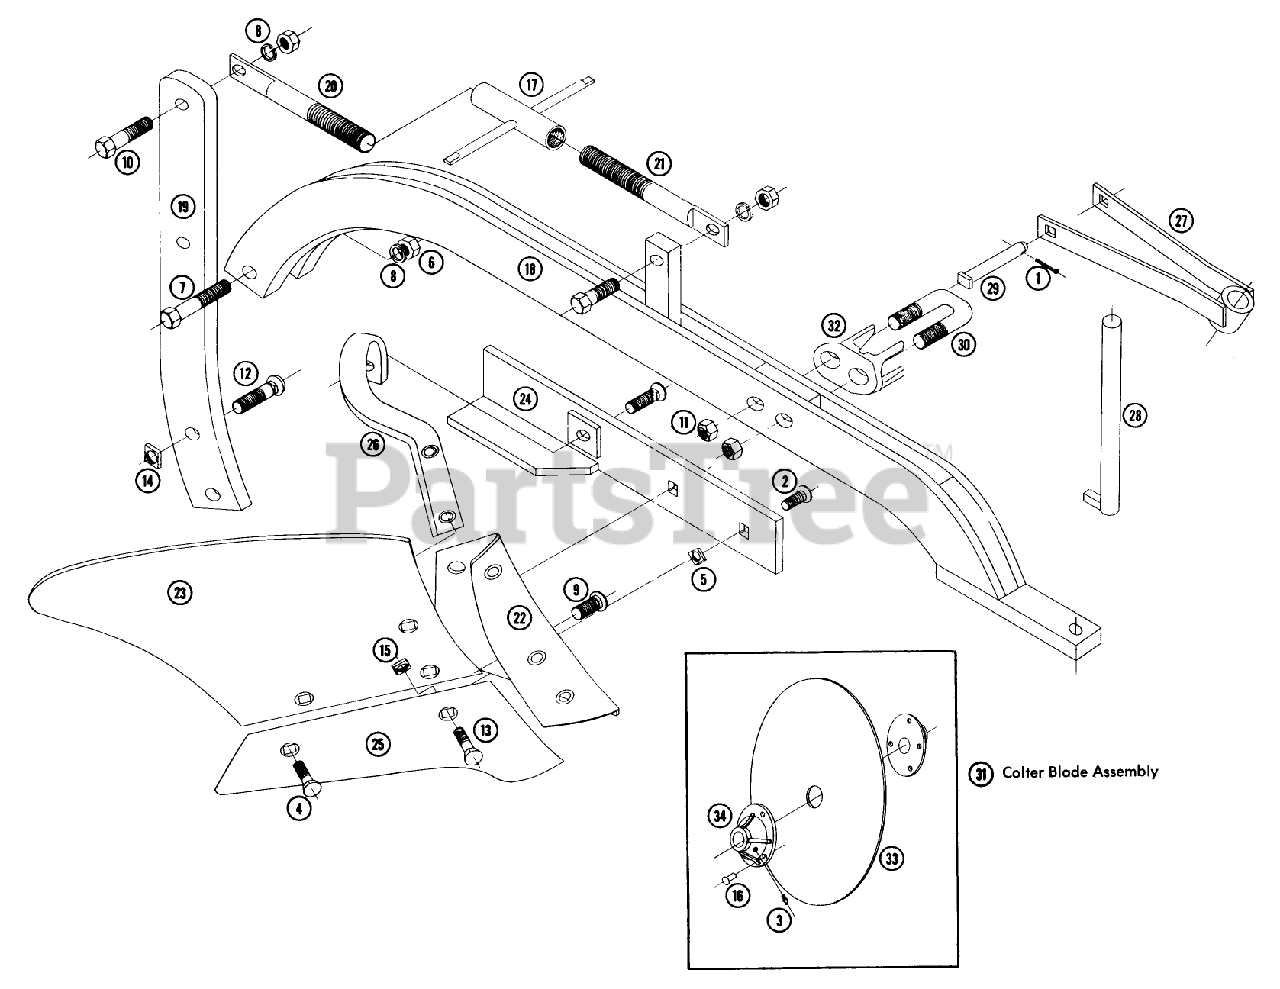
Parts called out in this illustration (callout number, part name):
1	Cotter Key
2	Bearing
4	Plow Bolt w/nut
5	Sq. Nut 3/8-16
6	63543/63567 REAR MT
7	1077 WH '67 TRACTOR
8	Lockwasher
9	Plow Bolt 1/2-13 x 1-1/2
10	Hex Hd. Cap Screw 1/2-13 x 1-1/2
11	Nut 5/8 x 18
12	Carriage Bolt 1/2-13 x 1-3/4
13	Plow Bolt 7/16-14 x 1
14	Sq. Nut 1/2-13
15	Sq. Nut 7/16-14
16	Rd. Hd. Rivet 17/64 x 5/8
17	Coupling-Adjusting
18	Beam Assembly W/A
19	Bar-Rear Vertical Member
22	Frog
23	Mold Board
24	Landslide
25	Point
26	Spreader
27	Standard Assembly
28	Rod-Swivel
29	Pin-Pivot
30	U Bolt
31	Colter Blade Assembly
32	Clamp Coulter
33	Blade 10" Dia.
34	Hub-Blade
